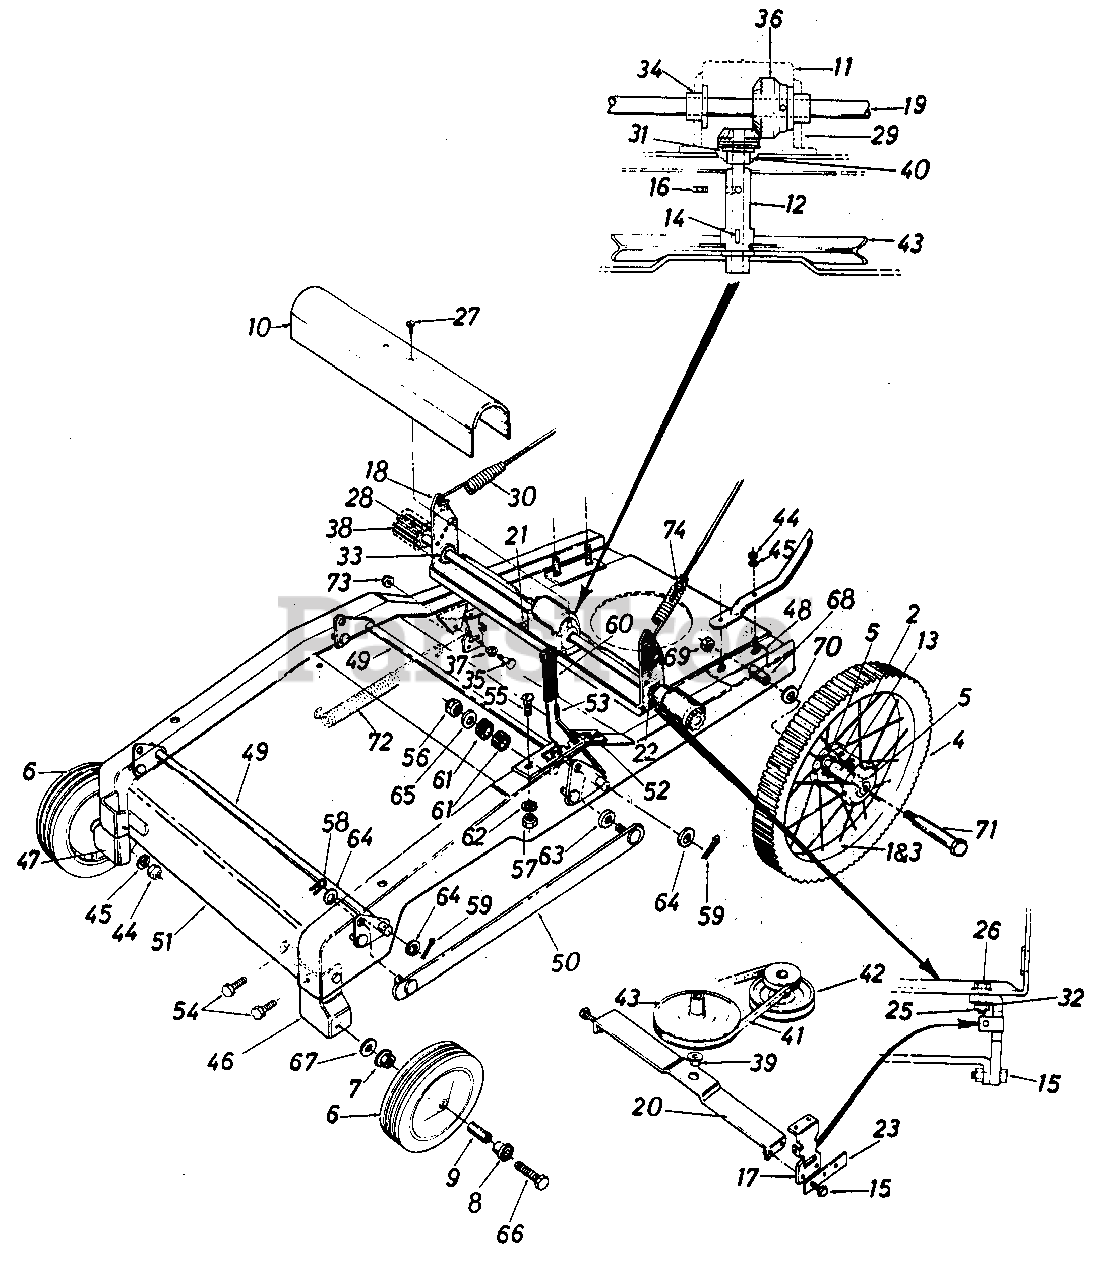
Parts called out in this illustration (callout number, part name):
1	16" Wheel Ass'y. Comp.-Rear
2	Oil Cap
3	Rear Wheel-Rim Only
4	Rear Wheel-Tire Only 16 x 1 .75
5	Ball Brg. .630" I.D.
6	Wheel Ass'y. Comp.-Front-8 x 1.75
7	Flanged Ball Brg. 3/8" I.D.
8	Flanged Ball Brg. 1/2" I.D.
9	Spacer 3/8" I.D.
10	Top Drive Frame Cover
11	Gear Box Cover
12	Pinion Ass'y.
13	Wheel Spacer
14	#2 Woodruff Key 3/32 x 1/2" Dia. Hdn.
15	Hex Sems Bolt 5/16-18 x 1.00" Lg .
16	Set Scr. 5/16-18 x .25" Cup
17	Bottom Drive Frame
18	Top Drive Frame Ass'y.
19	Drive Shaft
20	Bottom Drive Frame Ass'y.
21	Hex Self-Tap Scr. 1/4-20 x .62" Lg.
22	Collar 5/8" I.D.
23	Drive Frame Stop
25	Hex Nut 5/16-18 Thd.*
26	Hex Sems Bolt 5/16-18 x .75" Lg.*
27	Hex Wash. Hd. AB-Tap Scr. #8 x .50" Lg.
28	Spring Pin 3116" Dia. x 1.12" Lg.
29	Gear Box
30	Extension Spring
31	"O"-Ring
32	L-Wash. 5/16" I.D.
33	Ball Brg. .630" I.D.
34	Flange Brg. .630" I.D.
35	Shld. Bolt .443" Dia. x .330
36	Bevel Gear .62" I.D. 28 Teeth
37	Pivot Slide
38	Drive Pinion
39	Hex Flange Brg. .503" I.D.
40	Flange Brg. .503" I.D. w/ Groove
41	3V-Belt 28" Lg.
42	Double Pulley
43	3/8" V-Pulley .502" I.D. x 6.5" O.D.
44	Hex L-Nut 3/8-16 Thd.
45	L-Wash. 3/8" I.D.
46	Wheel Brk't. Ass'y.-L.H.
47	Wheel Brk't. Ass'y.-R.H.
48	Rear Wheel Brk't. Ass'y.
49	Lift Bracket Shaft Ass'y.
50	Connecting Link Ass'y.
51	Frame
52	Lift Handle Support Brk't.
53	Lift Handle
54	Hex Sems Bolt 5/16-18 x .75" Lg.
55	Carriage Bolt 5/16-18 x .62" Lg.
56	Hex Ins. L-Nut 3/8-24 Thd.
57	Hex ut 5/16-18 Thd. *
58	Intern. Cot. Pin 5/16" Dia.
59	Cot. Pin 118" Dia. x 1.00" Lg. *
60	Grip-Black
61	Rubber Wash. .33" I.D. x .87" O.D.
62	L-Wash. 5/16" I.D.
63	Fl-Wash. .406" I.D. x 1.25" O.D. x .164
64	Fl-Wash. .510" I.D. x 1.0" O.D. x .060
65	Fl-Wash. .385" I.D. x.87" O.D. x .06
66	Hex Bolt 3/8-16 x 2.00" Lg.
67	Bell-Wash. .400" I.D. x .88" O.D.
68	Spacer. 523" I.D. x .640" O.D. x 1.955
69	Hex Top L-Nut 3/8-16 Thd.
70	Fl-Wash. .531" I.D. x.93" O.D.
71	Shld. Bolt .498" Dia. x 4.755
72	Extension Spring .56" O.D. x 8.25" Lg.
73	Hex Ins. L-Nut 5/16-18 Thd.
74	Hex Ins. L-Nut 1/4-20 Thd.
